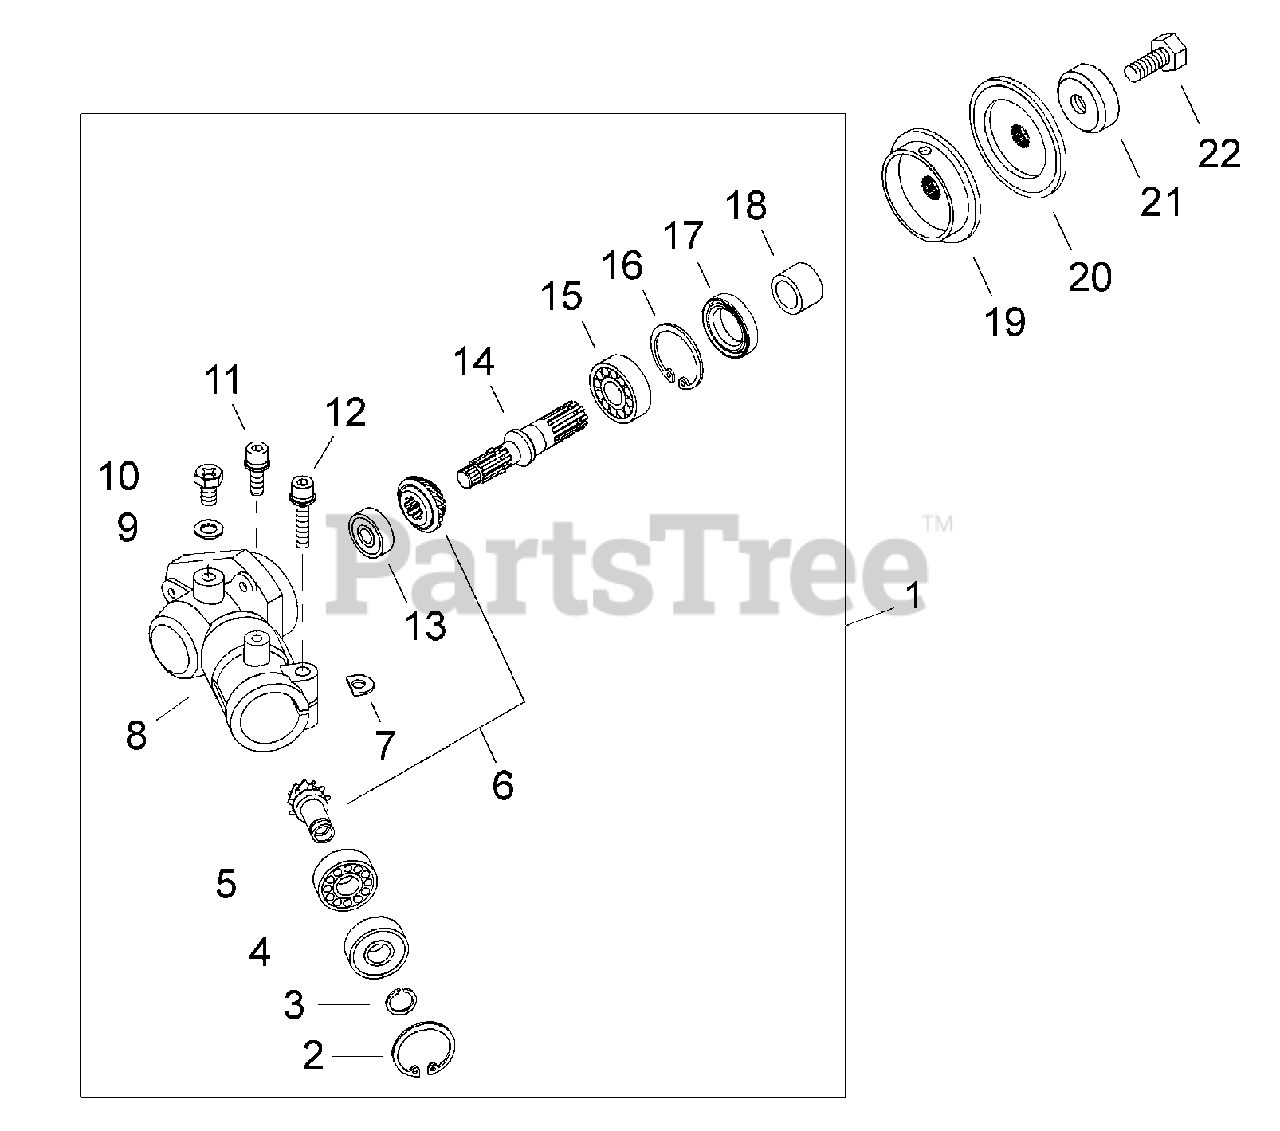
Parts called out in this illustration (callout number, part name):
1	GEAR CASE ASSY
2	RING, RETAINING - 24
3	RING, RETAINING
4	BEARING, BALL - 609ZZ
5	BEARING, BALL - 609
6	GEAR SET
7	SHIM
8	CASE, GEAR
9	WASHER - 6
10	BOLT - 6X10
11	SCREW - 5X16
12	SCREW - 5X25
13	BEARING, BALL - 608DDU
14	GEAR - SHAFT
15	BEARING, BALL - 6001
16	RING, RETAINING - 28
17	SEAL, OIL
18	COLLAR
19	HOLDER - A
20	ADAPTOR, BLADE - LOWER
21	GUARD
22	BOLT - 8 -- LEFT HAND
